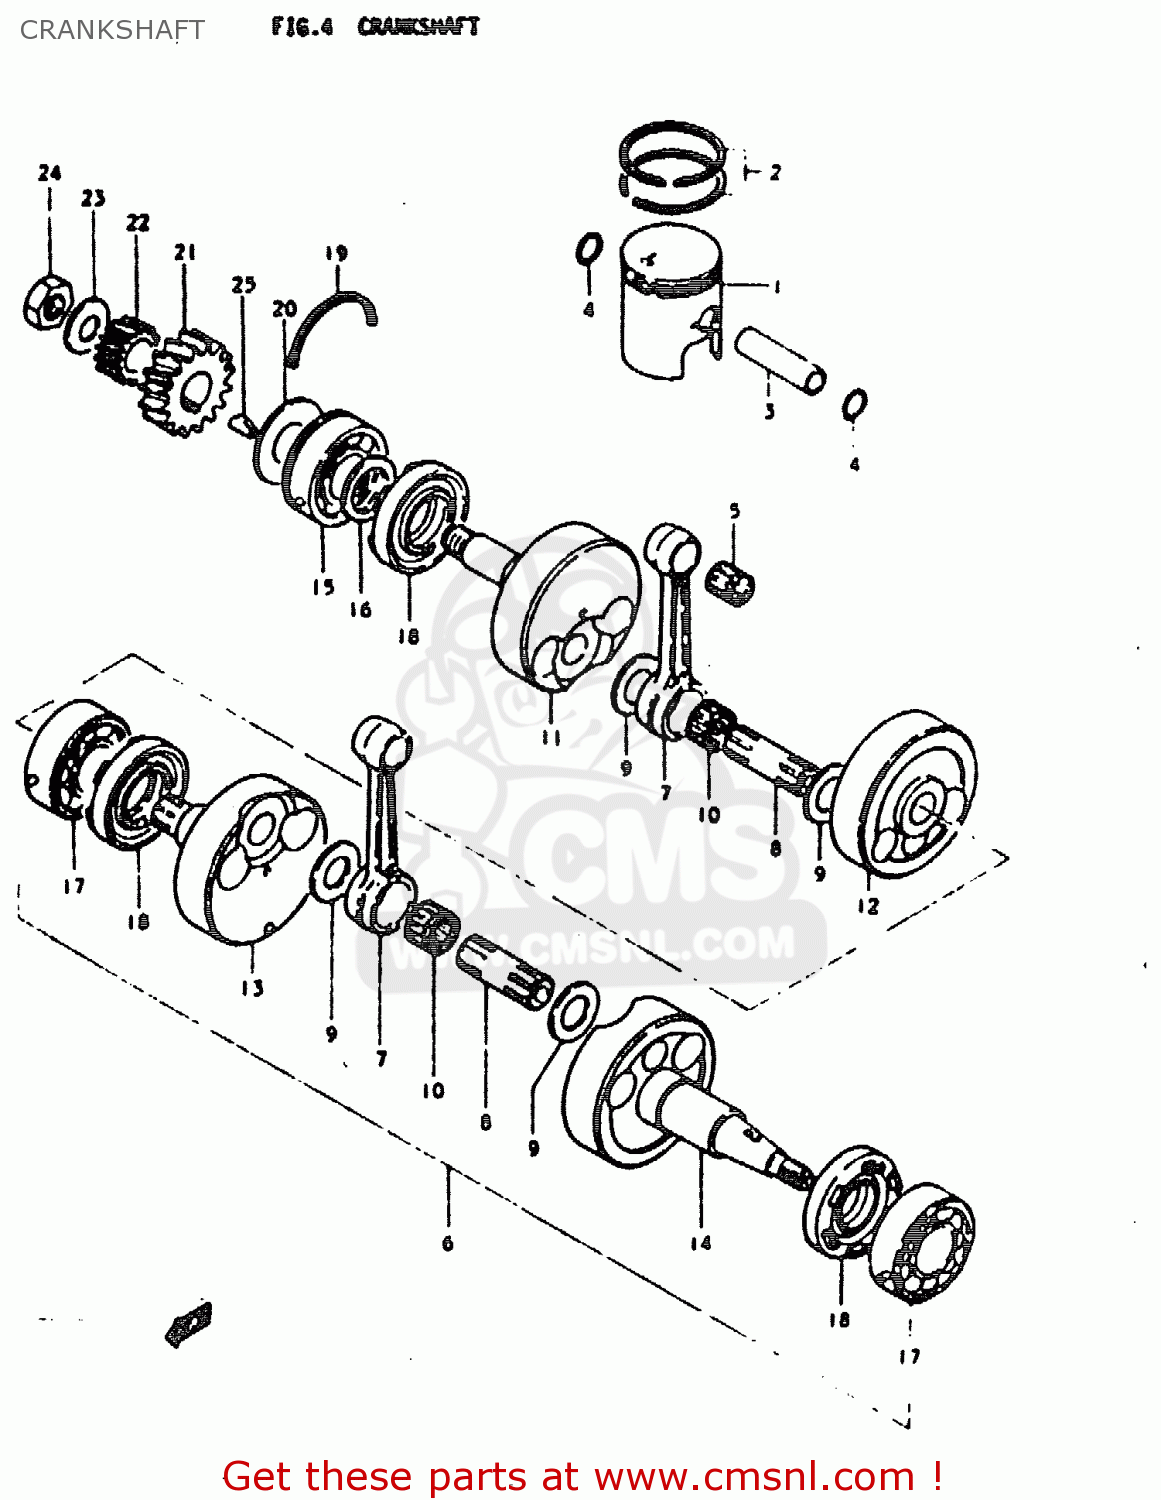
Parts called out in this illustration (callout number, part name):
1	PISTON
2	RING SET,PISTON
3	PIN,PISTON 14MM
4	RING,SNAP 14MM
5	BEARING
6	CRANKSHAFT ASSY
7	CONNECTING ROD
8	PIN,CRANK
9	WASHER(19X32X1)
10	BEARING(19X25X16)
11	CRANKSHAFT, RH
12	WEB, CRANK
13	CRANKSHAFT, MIDDLE
14	CRANKSHAFT, LH
15	BEARING(25X62X17)
16	WASHER
17	BEARING
18	SEAL,OIL(30X62X11)
19	C RING
20	WASHER(20X48X1)
21	GEAR, PRIMARY DRIVE
22	GEAR, TACHOMETER DRIVE NO.1
23	WASHER
24	NUT
25	KEY
